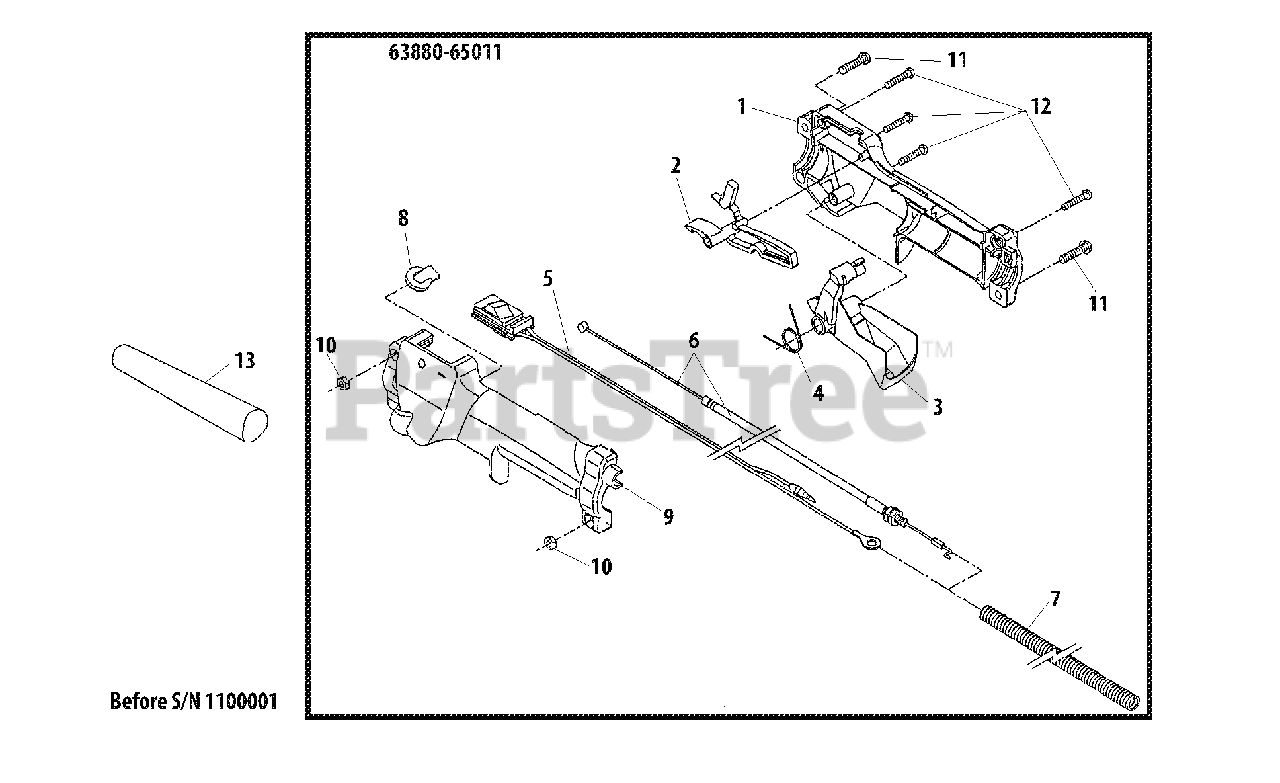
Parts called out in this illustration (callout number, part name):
1	HANDLE, CONTROL - RIGHT
2	LEVER, LOCK
3	LEVER
4	SPRING
5	SWITCH, IGNITION
6	CABLE, THROTTLE
7	TUBE
8	PLUG
9	HANDLE, CONTROL - LEFT
10	NUT - 5
11	SCREW - 5X20
12	SCREW - 4X20 -- TAPPING
13	COLLAR
63880-65011	THROTTLE LEVER ASSY
